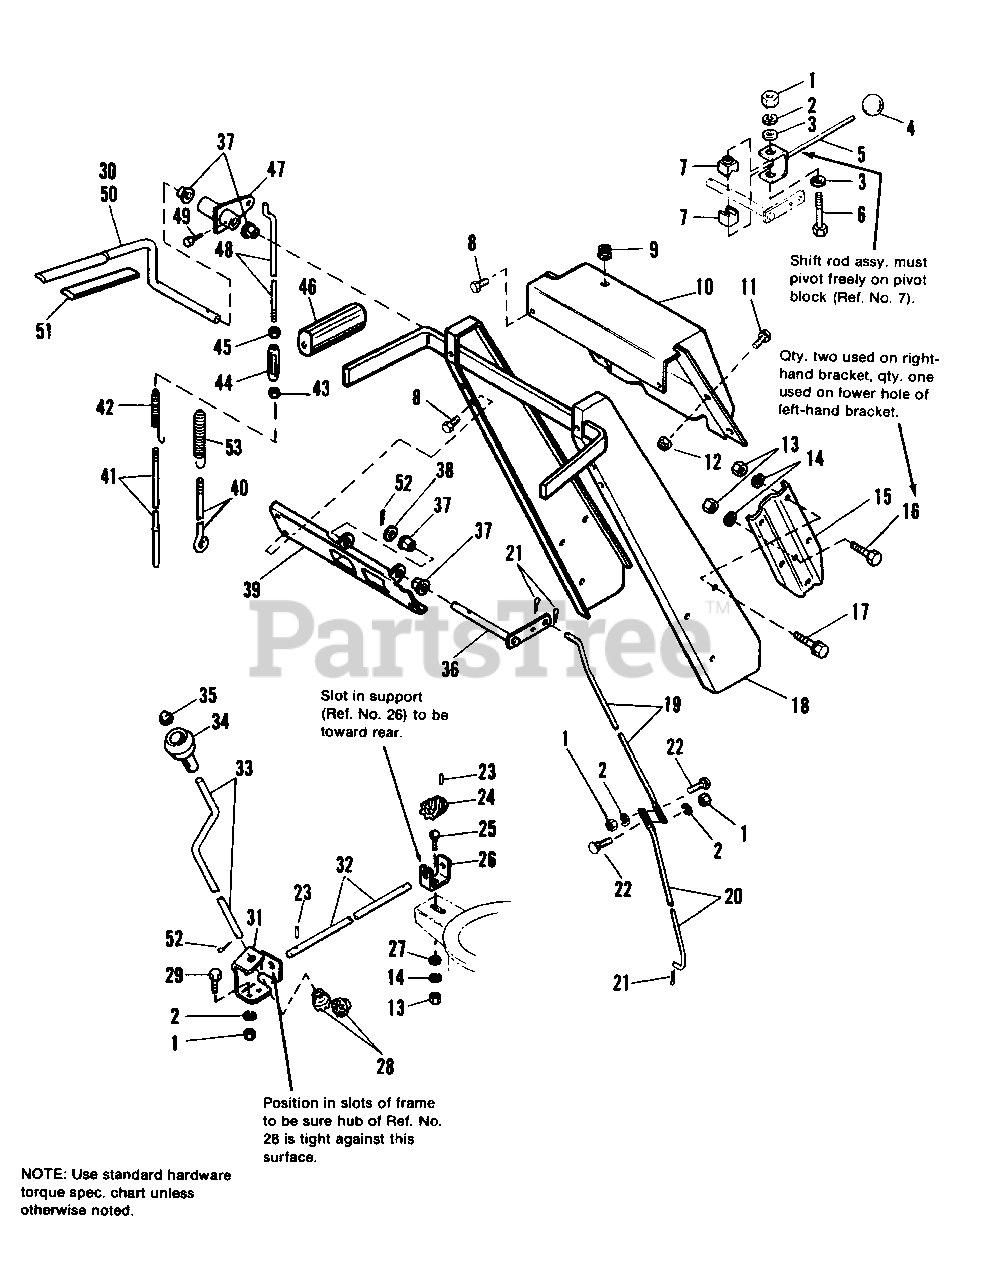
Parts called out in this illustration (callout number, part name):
1	NUT, Hex, 1/4-20
2	LOCKWASHER, 1/4
3	WASHER, Flat, 1/4
5	SHIFT ROD ASSY.
6	CAPSCREW, Hex Hd., 1/4-20 x 2-1/4
7	BLOCK, Pivot
8	SCREW, Taptite, 1/4-20 x 1/2
9	BUSHING, Plastic
10	DASH, Handle
11	CAPSCREW, Washer hd., 1/4-20 x 3/4
12	NUT, Nylon Lock, 1/4-20
13	NUT, Hex, 5/16-18
14	LOCKWASHER, 5/16
15	BRACKET, Handle Mfg.
16	CAPSCREW Hex Hd., 5/16-18 x 3/4
17	CAPSCREW, Whizlock, 5/16-18 x 3/4
18	HANDLE ASSY.
19	ROD, Shift-Upper
20	ROD, Shift-Lower
21	PIN, Cotter, 3/32 x 3/4
22	BOLT, Carriage, 1/4-20 x 3/4
23	PIN, Roll, 1/8 x 3/4
24	WORM, Chute
25	BOLT, Carriage, 5/16-18 x 3/4
26	SUPPORT, Worm
27	WASHER, Flat, 5/16
28	GEAR, Universal
29	CAPSCREW, Hex Hd., 1/4-20 x 3/4
30	HANDLE, Clutch, L.H.
31	SUPPORT, Universal Gear
32	ROD, Chute Worm
33	ROD, Chute Control
34	KNOB, Spinner
35	PALNUT
36	PIVOT ROD ASSY.
37	BUSHING, Plastic
39	BRACKET, Shift Control
40	ROD, Clutch-Lower, Auger
41	ROD, Clutch-Lower, Traction
43	NUT, Hex, #10-24, R.H.
45	NUT, Hex, #10-24, L.H.
46	GRIP, Handle bar
47	CLUTCH LEVER ASSY.
48	ROD, Clutch-Upper
49	SCREW, Taptite, #10-24 x 1
50	HANDLE, Clutch, R.H.
51	GRIP, Clutch
52	PIN, Cotter, 1/8 x 1
